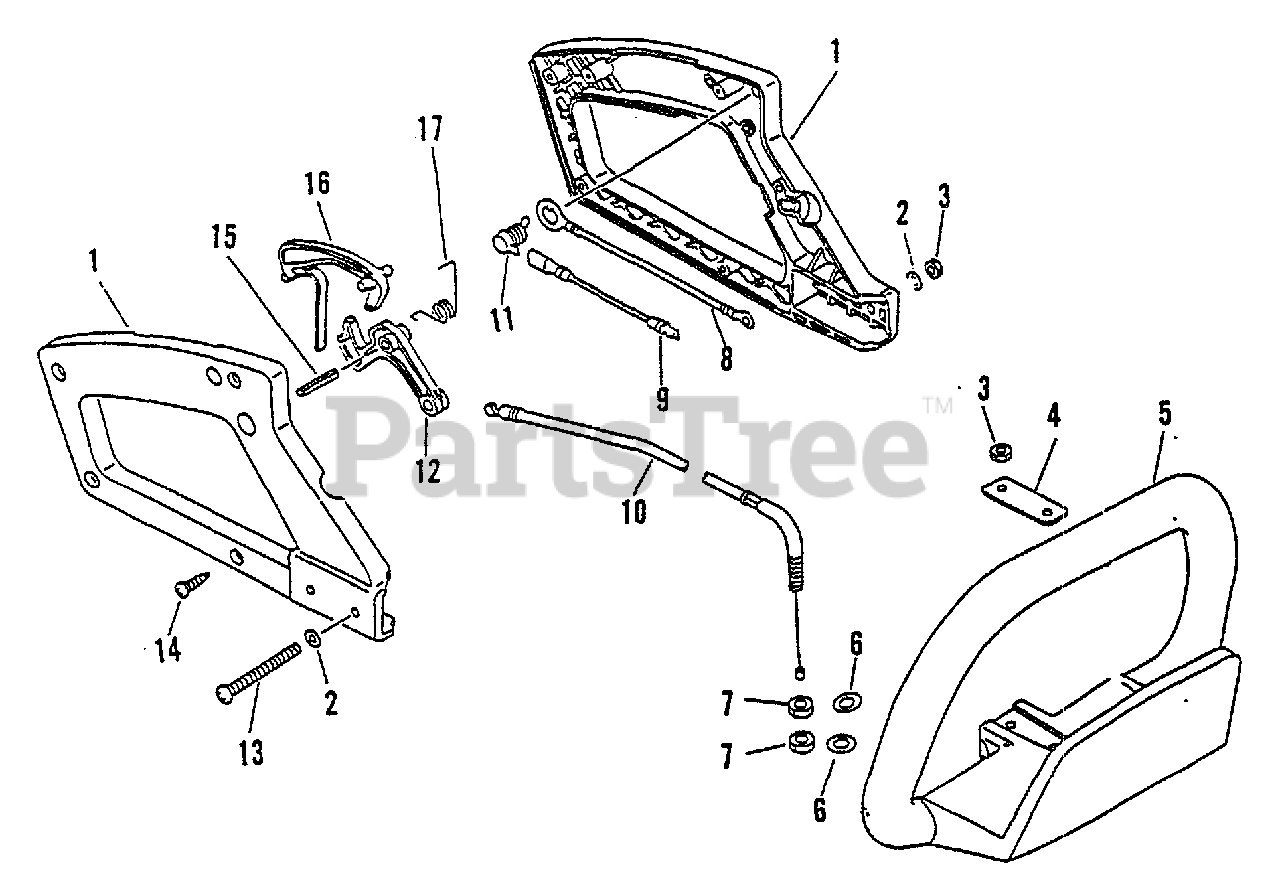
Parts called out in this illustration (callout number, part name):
1	HANDLE SET, REAR
2	WASHER, FLAT 5.5×10×0.8
3	NUT, LOCK M5
4	PLATE, EYE
5	HANDLE, SUPPORT
6	WASHER 6.5×11.5×0.8
8	LEAD - GROUND
9	LEAD - GROUND
10	CABLE, THROTTLE
11	SWITCH, ON-OFF
12	TRIGGER, THROTTLE
13	SCREW 5×50
14	SCREW 4×16
15	PIN, SPRING Ø5×25 MM
16	LOCKOUT, THROTTLE
17	SPRING, THROTTLE RETURN
